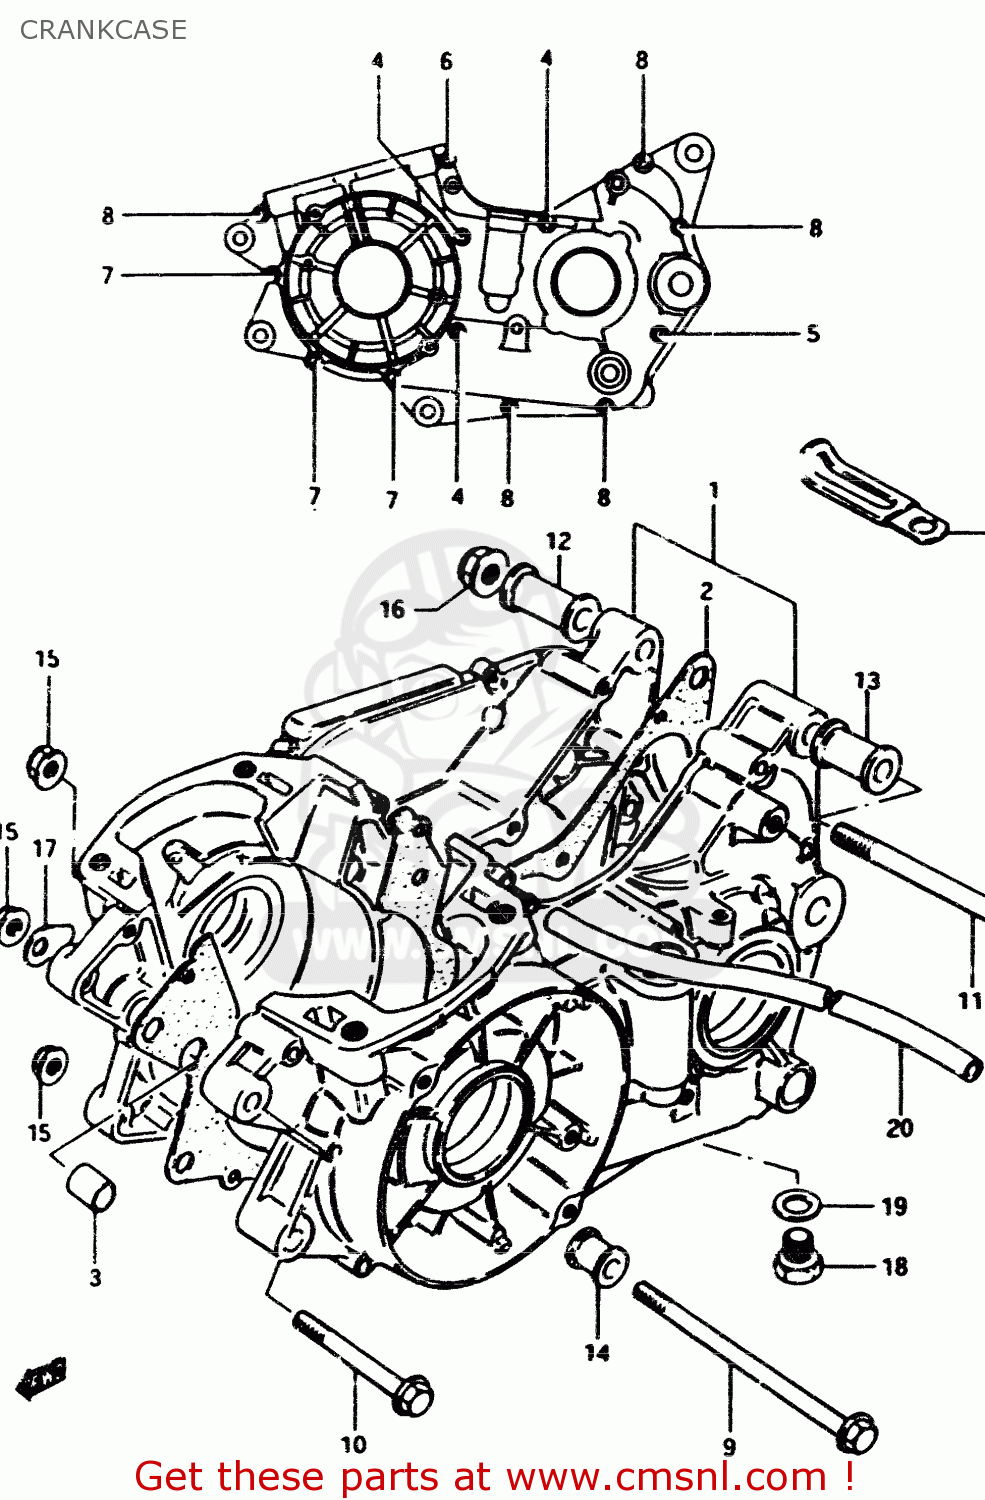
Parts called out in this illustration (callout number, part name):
1	CRANKCASE SET
2	GASKET,CRANKCASE
3	PIN
4	SCREW 6X65
5	SCREW
6	SCREW (6X45)
7	SCREW
8	SCREW (6X35)
9	BOLT 8X200
10	BOLT(8X75)
11	BOLT 10X215
12	SPACER,ENGINE MOUNT
13	SPACER,ENGINE MOUNT
14	SPACER,ENGINE MOUNT
15	NUT
16	NUT
17	WASHER
18	PLUG
19	GASKET(14X19.2X2) (NAS)
20	HOSE
21	CLAMP
